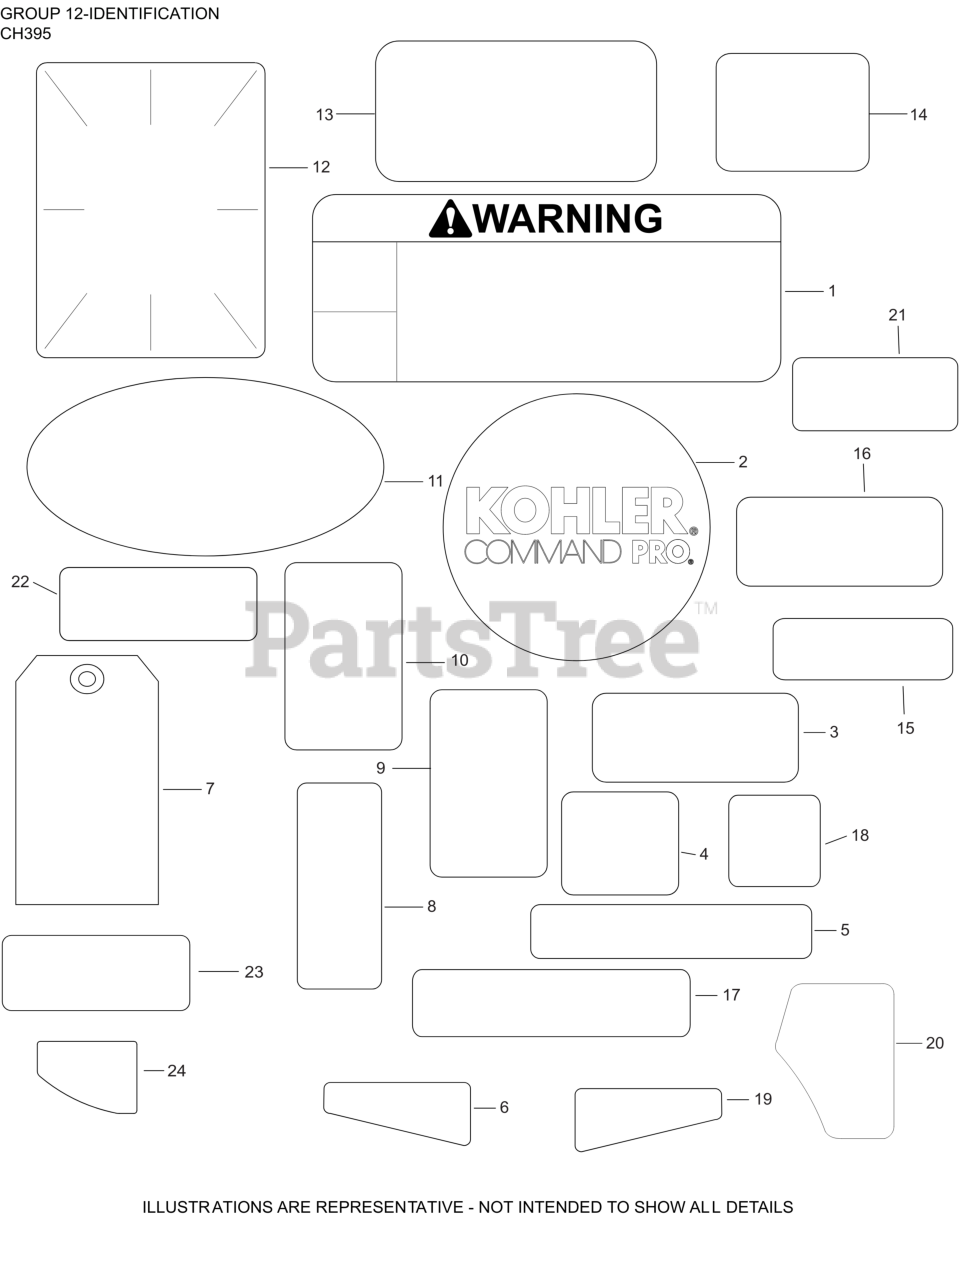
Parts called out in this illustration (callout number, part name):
1	DECAL, WARNING
2	LABEL, RECOIL 75MM
3	LABEL, CANADIAN COMPLIANCE
4	DECAL, BASE ARROW
5	DECAL, THROTTLE
6	DECAL, 9.5 HP/277cc/CH395
9	DECAL, SUN
10	DECAL, SNOW FLAKE
11	DECAL, QUAD CLEAN SILVER
12	LABEL, CLEAR LAMINATION
13	LABEL, MAINTENANCE (CKY)
16	DECAL, ETHANOL WARNING
18	LABEL, CHOKE
23	LABEL, FUEL SECURE
